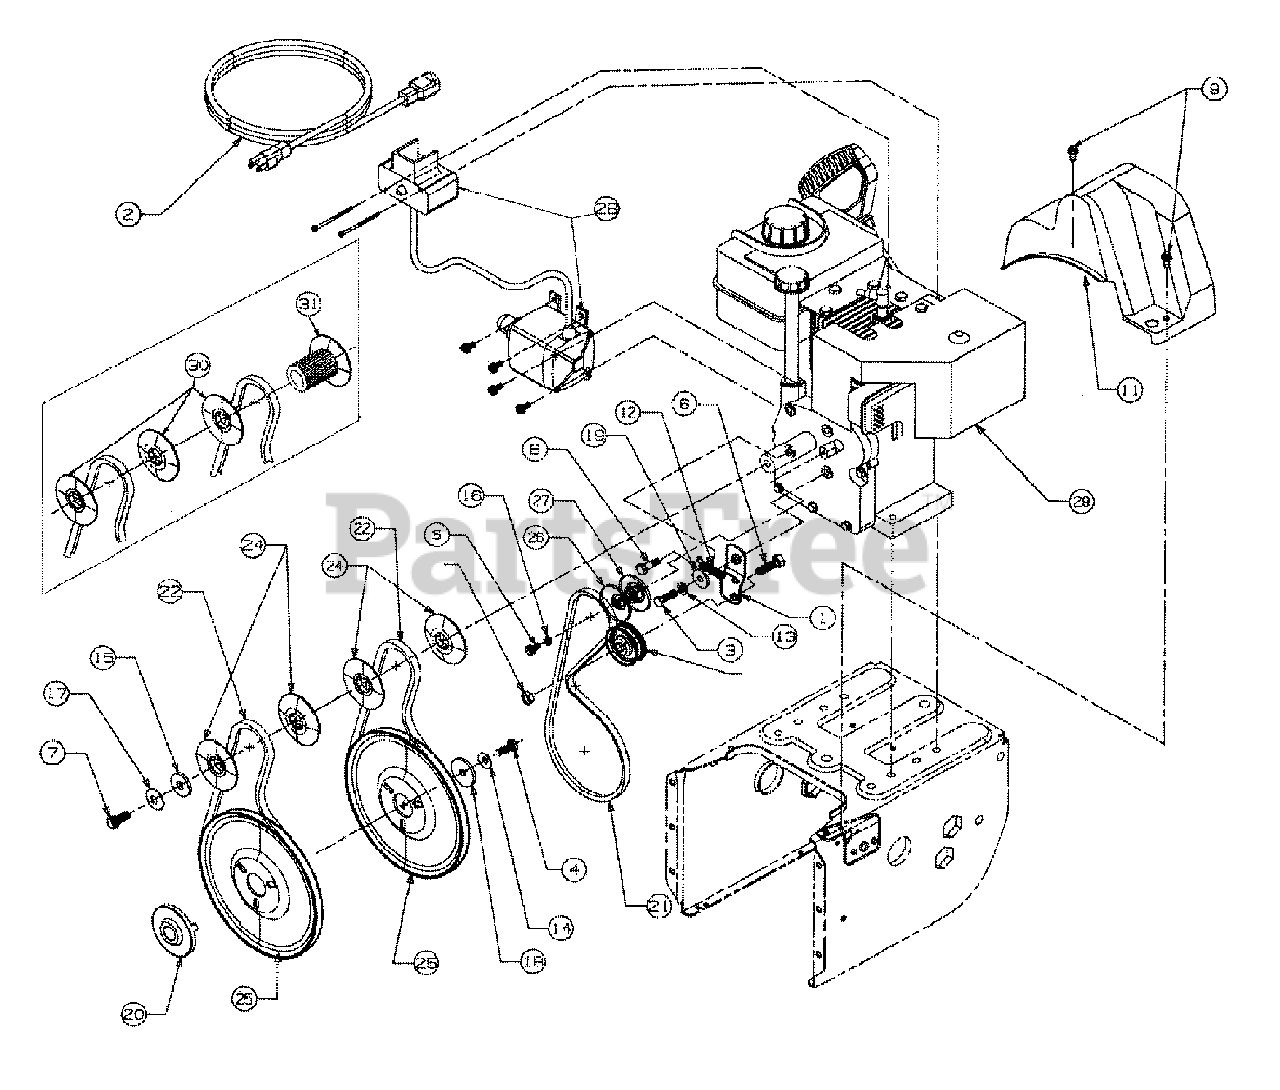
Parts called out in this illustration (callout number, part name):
3	Screw
4	Screw
5	Screw
6	Screw
7	Screw
8	Screw
9	Screw
10	Nut, Hex
11	Belt Cover
12	Spring
13	Washer-Lock
14	Washer-Bell
15	Flat Washer
16	Washer-Lock
17	Washer
18	Washer
19	Shoulder Spacer
20	Pulley Adapter
21	V-Belt
22	V-Belt
23	Idler, Flat
24	Pulley, Half
25	Pulley Auger
26	Pulley, Half
27	Pulley, Half
28	Starter
29	Engine
30	Pulley, Half
31	Pulley, Half
